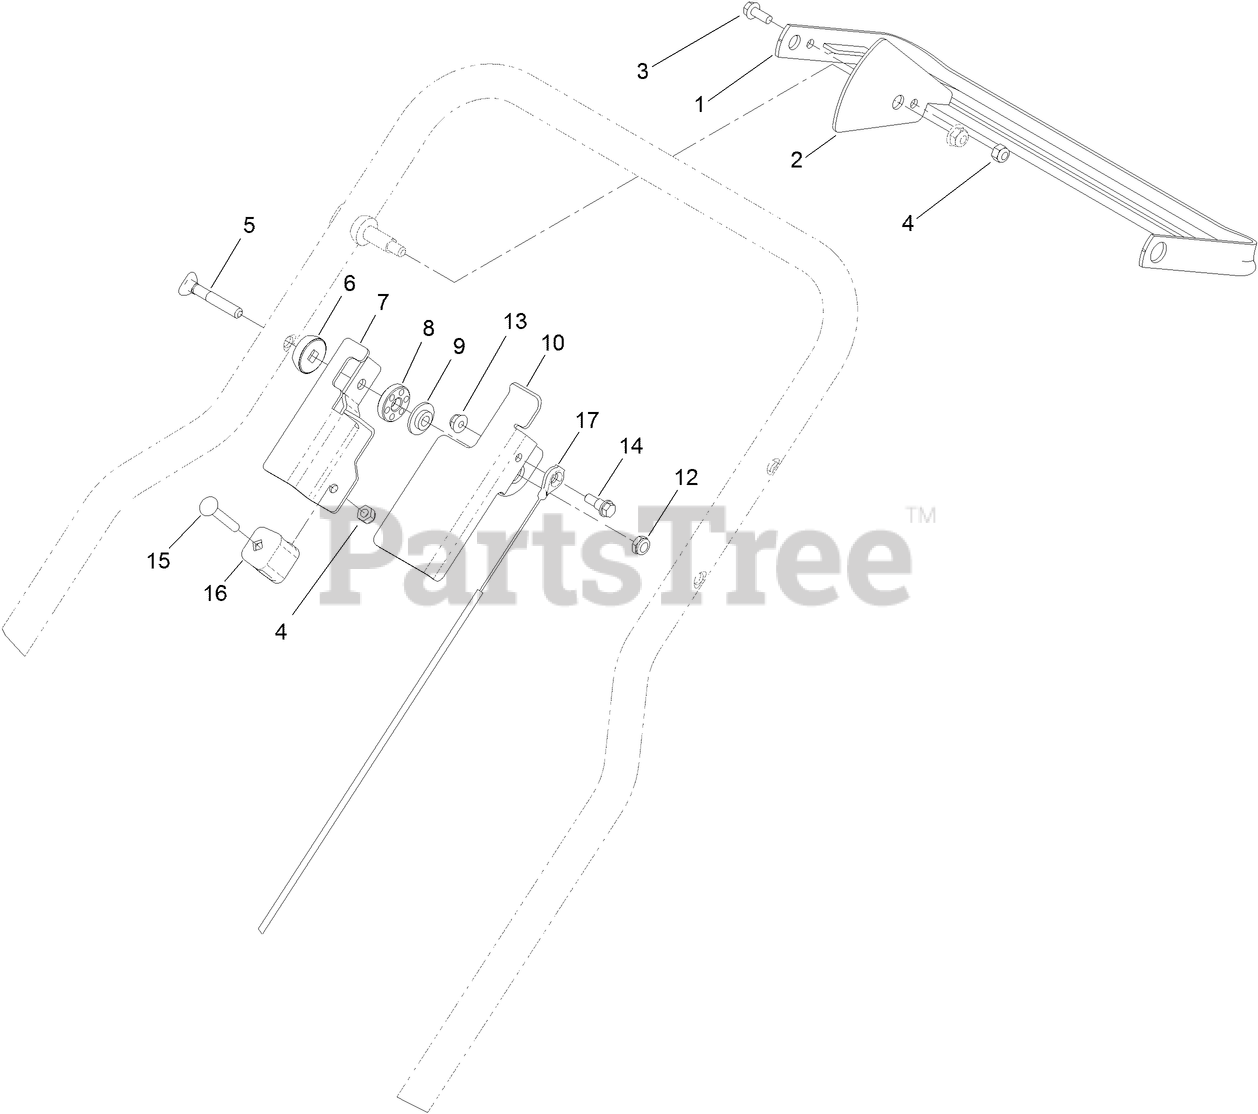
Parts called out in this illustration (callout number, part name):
1	BAR-CONTROL
3	SCREW-HWH
4	NUT-LOCK, NI
5	SCREW-HANDLE
6	WASHER-CURVED
7	BRACKET-ANCHOR, CABLE
8	WASHER
9	WASHER-STEPPED
10	LEVER-BRAKE
12	NUT-LOCK, NI
13	NUT-HF
14	BOLT-SHOULDER
15	SCREW-CARR
16	ANCHOR-CABLE
17	CABLE-BRAKE, PARKING
